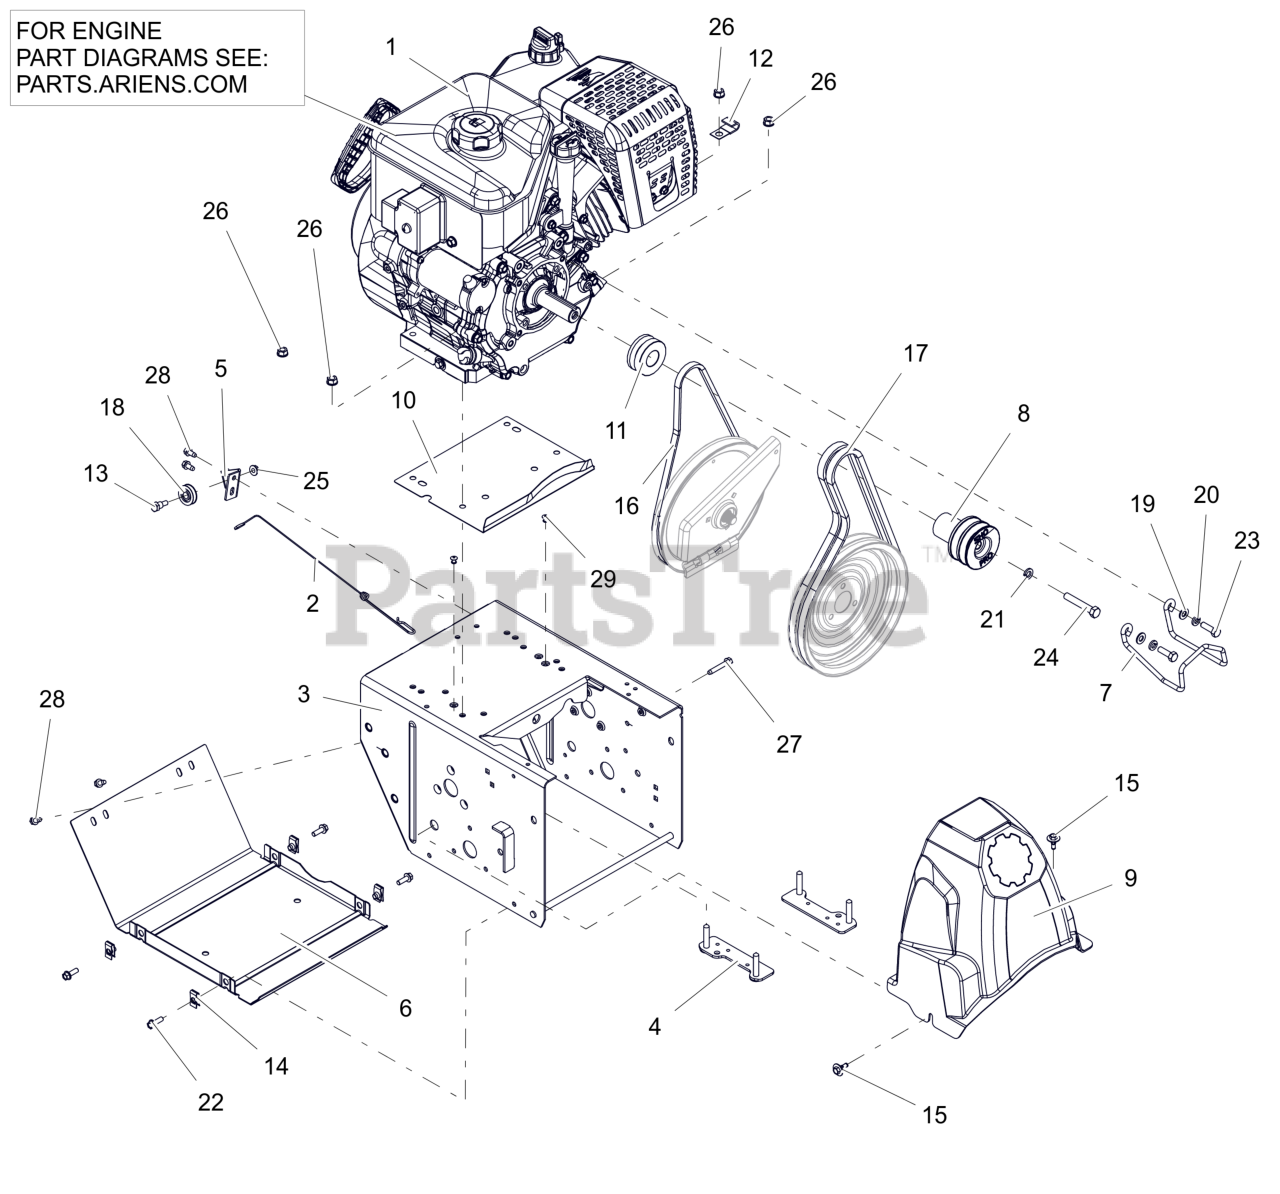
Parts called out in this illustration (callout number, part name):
1	ENGINE, AX420 GEN 3 240V/60W
2	CABLE, LOWER TRACTION,SS & PRO
3	FRAME, MAIN - PRO (WELDMENT)
4	STRAP, BOLT-LARGE
5	BRKT, CABLE PULLEY
6	COVER, BOTTOM
7	FINGER, BELT
8	SHEAVE,ATTACHMENT-SHO 2 GRV
9	COVER, BELT
10	BAFFLE, WATER - LARGE BLOCK
11	SHEAVE, TRACTION (KEYLESS)
12	J-CLAMP
13	BOLT, SHLDR -.375 X .375 X .25-20
14	NUT-RTNR .25-20X.56
15	SCR-TAP .25-20X.5 CAPTIVE
16	V-BELT, 3L-WRAPPED
17	V-BELT, HA-RAW EDGE (SET)
18	PULLEY, CABLE
19	WSHR,FLT .344X.688X.065 ZCC
20	WSHR, LK-HVY .312X.097 ZCC
21	WSHR,LK-REG .375X.094 ZCC
22	BLT, HWH .25-20X.75 G5 ZCC
23	BLT, HEX 0.3125-24X1 G5 ZCC
24	BLT, HEX .38-24X2.25 G5 ZCC
25	NUT-LK-TOP-FLG .250-20 GF ZCC
26	NUT,LK-CTR-FLG .31-18 GF ZCC
27	SCR,TAP .25-20X1.50 HWH TR ZCC
28	SCR-TAP .25-20X.50 HWH ZCC
29	RVT, POP .1875 ZCC
